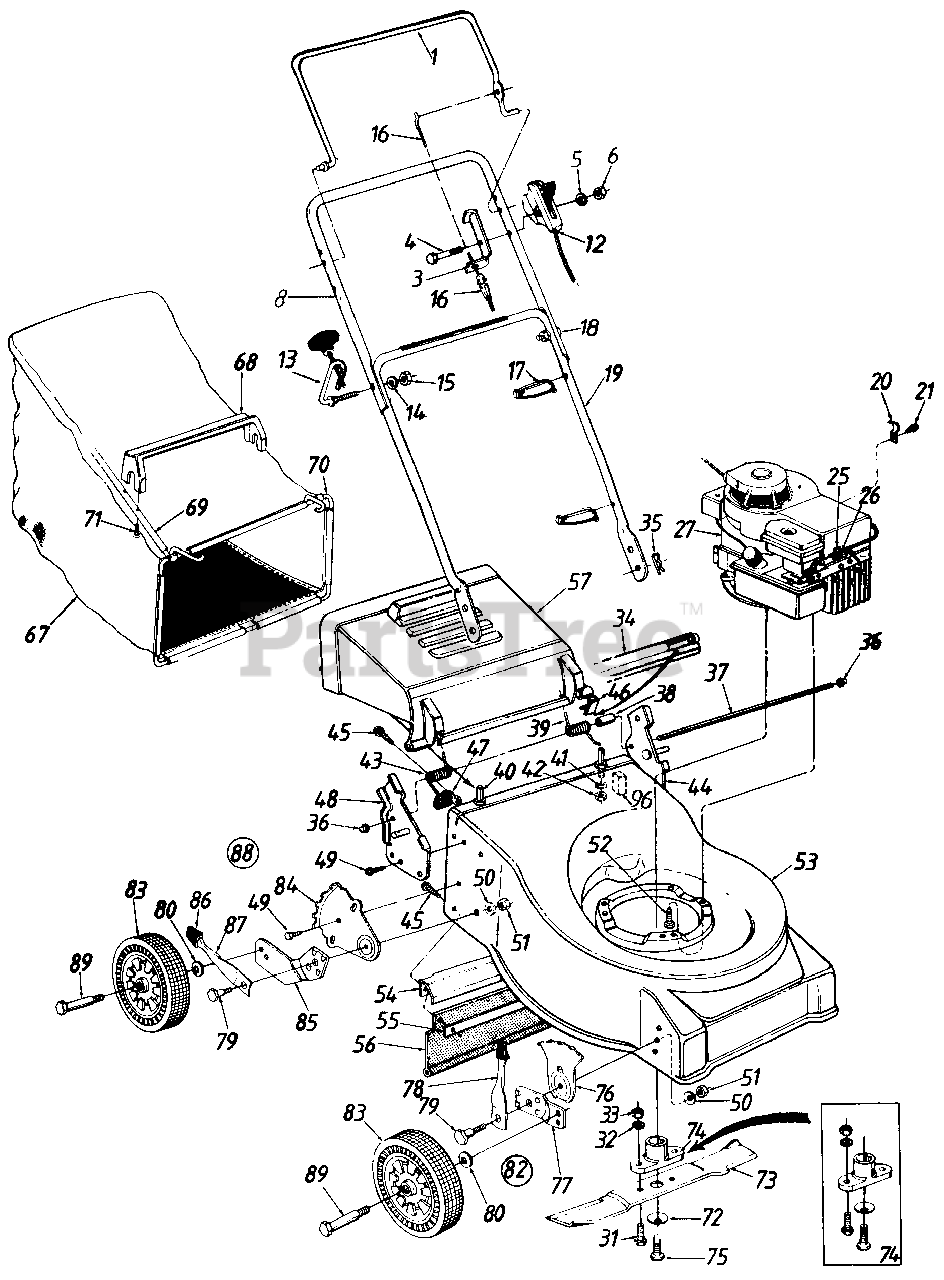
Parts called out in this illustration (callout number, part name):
1	Control Handle Ass'y.
3	Cable Brkt.
4	Hex Bolt 1/4-20 x 1.75" Lg.
5	Spr. Wash. 1/4" I.D.
6	Hex Nut 1/4-20 Thd.
13	Rope Guide Bolt
14	L-Wash. 5/16" I.D.
15	Hex Nut 5/16-18 Thd.
16	Control Cable 43"
17	Cable Tie
18	Curved Carriage Bolt 5/16-18 x 1.38" Lg.
19	Lower Handle
20	Cable Clamp
21	Hex B-Tap Scr. #10 x .38" Lg.
25	Cable Clamp
26	Hex AB-Tap Scr. #8 x .5" Lg.
27	Engine
31	Hex Bolt 3/8-24 x 1"
32	L-Wash. 3/8" I.D.
33	Hex Nut 3/8-24 Thd.
34	Seal Extrusion
35	Int. Cotter Pin 5/16" Dia.
36	Cap Speed Nut
37	Hinge Pin 17.75" Lg.
38	Spacer.255" I.D.
39	Torsion Spring L.H.
40	Shld. Pin 3/8-24 x 1.43" Lg.
41	L-Wash. 3/8" I.D.
42	Hex Jam Nut 3/8-24 Thd.
43	Torsion Spring R.H.
44	Handle Brkt. Ass'y. L.H.
45	Torx Mach. AB-Tap Scr. 1/4 X .62" Lg.
46	Deflector Plug
47	Corner Plug
48	Handle Brkt. Ass'y. R.H.
49	Hex L-Wash. AB-Tap Scr. 1/4 x.62" Lg.
50	Bell-Wash. .39" I.D.
51	Hex Nut 3/8-16 Thd.
52	Hex L-Wash. Hd. Scr. 3/8-16 x 1" Lg.
57	Rear Chute Deflector
67	Grass Bag
68	Bag Handle
70	Front Catcher Frame
71	Hex AB-Tap Scr. #12 x 1.25" Lg.
72	Bell-Wash..39" I.D.
73	21" Blade
74	Blade Adapter Kit
75	Hex Bolt 3/8-24 x 1.5" Lg.
76	Height Adj. Plate
78	Spring Lever Ass'y. w/Knob
79	Shld. Bolt .50" Dia. x .357"
80	Bell-Wash. .38" I.D. x .88" O.D.
82	Height Adj. Ass'y. Comp. R.H.
83	Wheel Ass'y. Comp.
84	Index Plate
85	Pivot Bar R.H.
86	Spring Lever Knob
87	Spring Lever
88	Rear Height Adj. Ass'y. Comp. R.H.
89	Axle Bolt
